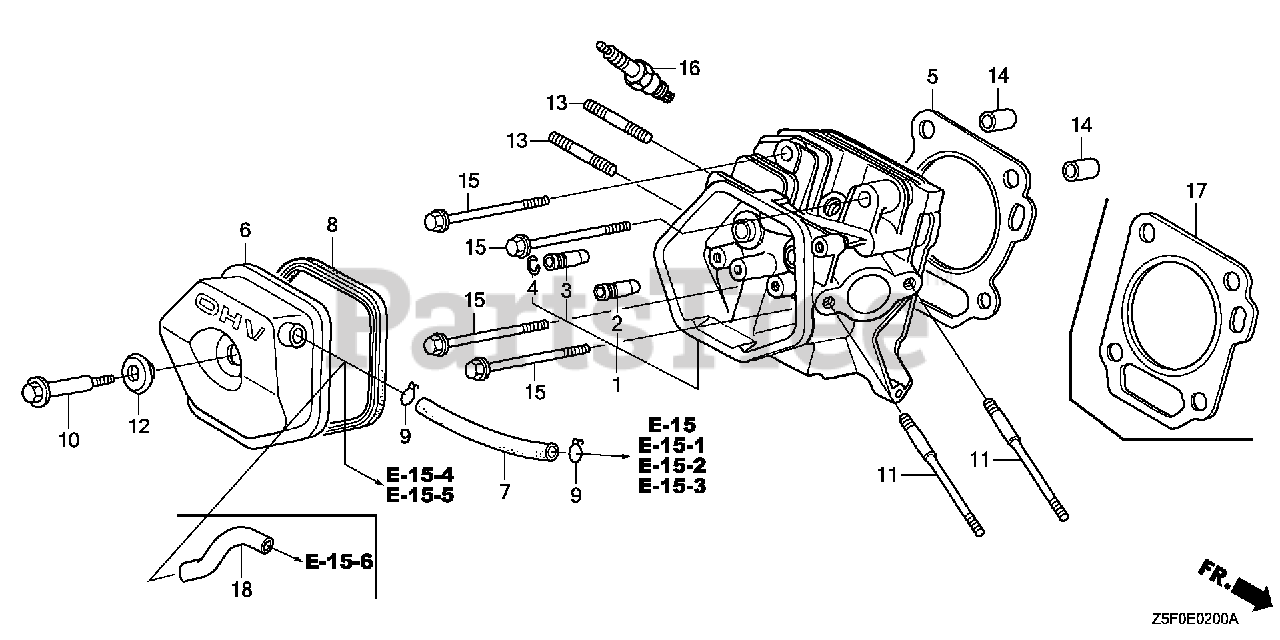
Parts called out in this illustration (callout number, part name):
1	CYLINDER HEAD
2	GUIDE, VALVE (OS)
3	GUIDE, EX. VALVE (OS)
4	CLIP, VALVE GUIDE
5	GASKET, CYLINDER HEAD
6	COVER, HEAD
7	BULK HOSE, VACUUM (11X1000) (Honda Code 4537312). (11X105)
8	GASKET, CYLINDER HEAD COVER
10	BOLT, HEAD COVER
11	BOLT, STUD (8X123)
12	WASHER, HEAD COVER
13	BOLT 2, STUD (8X32)
14	PIN A, DOWEL (12X20)
15	BOLT, FLANGE (10X80)
16	SPARK PLUG (BPR5ES) (NGK)
16	SPARK PLUG (W16EPR-U) (DENSO)
16	SPARK PLUG (BPR6ES) (NGK)
16	SPARK PLUG (W20EPR-U) (DENSO)
